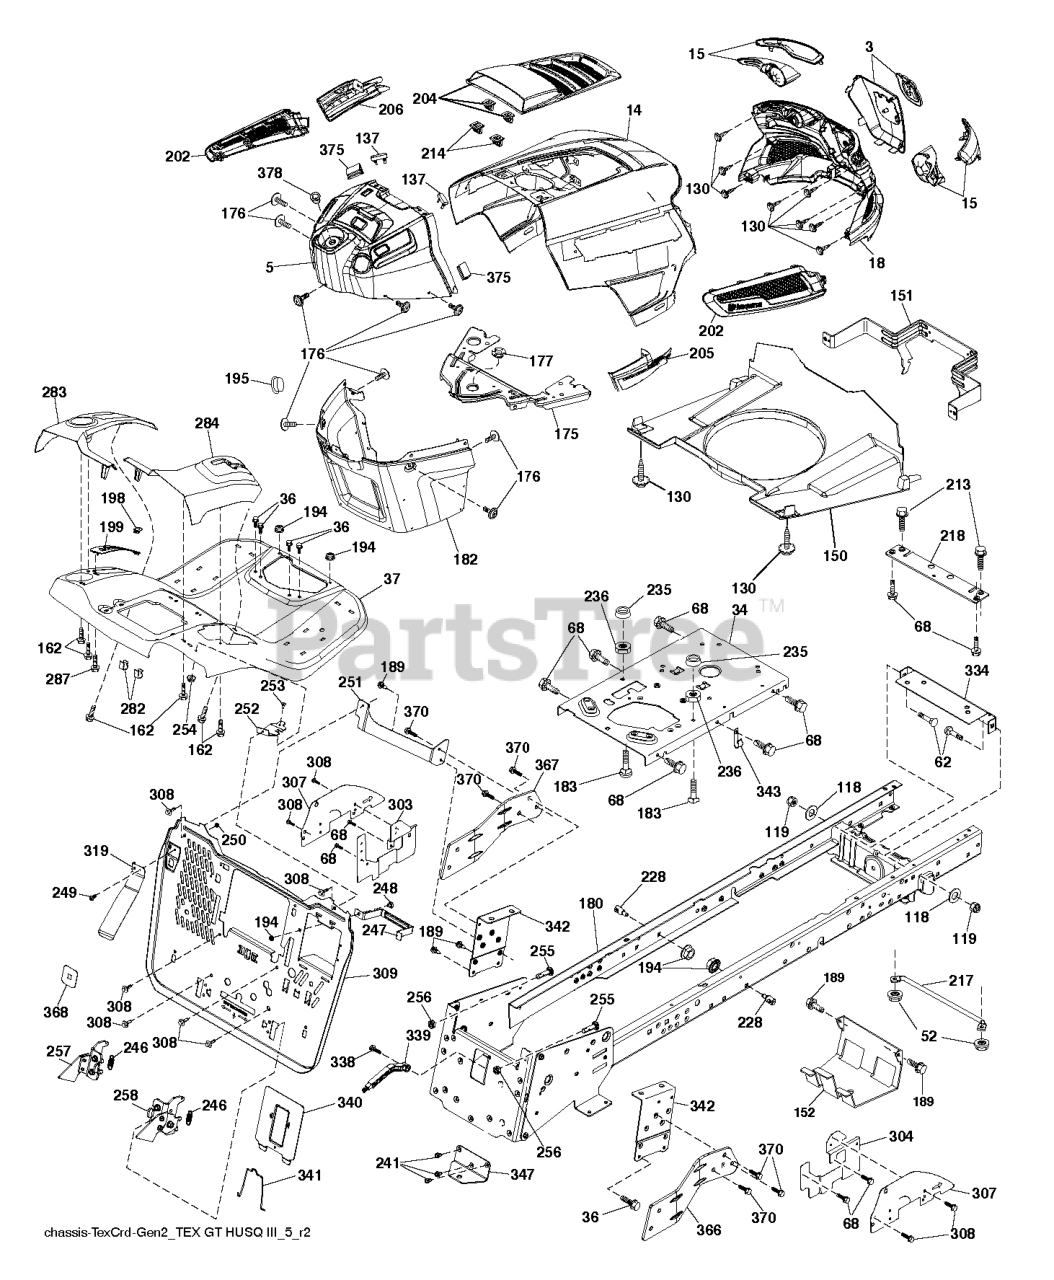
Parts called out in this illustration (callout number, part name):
5	DASH.ASM.W/BUMPERS.READYSTART
14	HOOD.ASM.HUSQVARNA.GT.TEX.ORAN
15	Service Kit
36	SCREW 5/16"
37	FENDER.TEX.SRD.CRD.FRN.GUARDS
118	WASHER PLAIN WASHER 3/8 X 0.08
137	BUMPER DASH
150	AIR.DUCT.GTV.BLACK
151	BRACKET.PIVOT.HOOD.GT.HUSQ.II
152	SHIELD.BROWNING.W/TEX
175	PLATE.PNT.CROSSMEMBER.HUSQ/PRE
176	SCREW.#10-24X5/8.RN.QU
177	BUSHING STEERING
180	CHASSIS WELDMENT.CRD2.BKP_BLTS
182	DASH LOWER.HUSQ.PRED NO CRUISE
189	SCREW
195	PLUG.HOLE.DASH.LOWER.12V.BLK
198	INDICATOR.DECK.LIFT.RED
199	PLATE DECK LIFT
202	Vents
205	SIDE.TRIM.RH.GT.HUSQ.II
206	SIDE.TRIM.LH.GT.HUSQ.II.GRAY
213	SCREW HEXAGON HEAD SCREW 5/16-
214	CLIP.RETAINER.TINNER.
217	ROD.PIVOT.HOOD
218	X-PIECE.HOOD.STOP.NON/
228	STUD.W/"D"ANTI-ROTATION
236	NUT.CENTERLOCK.5/16-
246	SPRING.LTCH.BGR.GEN2.5.CRD.TEX
247	STRAP.BATTERY.TCRD.GEN2.5X431
248	BOLT.CARR.5/16-18X1/2
249	SCREW.BUTTONHD.10-24X1/2.(2 2)
251	BRACKET.PNT.LH.SUPP.BKPLT.EDIP
252	BRACKET.PNT.RH.SUPP.BKPLT.EDIP
253	BOLT CUP HEAD SQUARE NECK BOLT
254	NUT T
257	LATCH.ASM.BGR.LH.GEN2.5.STMPD
258	LATCH.ASM.BGR.RH.GEN2.5.STMPD
282	CLIP.RETAINER.CONSOLE.LT.HUSQ
283	CONSOLE.DECKLIFT.CRDII.498
284	CONSOLE.PEDAL.HYDRO
287	SCREW 1/4X20
303	SHIELD.LWR.LH.30DECK/CRD1&2
304	SHIELD.LWR.RH.30DECK/CRD2PEDAL
307	SHIELD.UPPER.CRD.SRD.ISO
308	BOLT.5/16-18UNCX3/4 W/SEMS.BLK
309	BACKPLATE.TEXCRD2.5.BAGGER.479
319	LEVER.PRSNC.BGR.TEX.CRD.GEN2.1
334	BRACKET.ENGINE
339	LEVER LEVER BAGGER
340	BATTERY.DOOR.TCRD.GEN2.5.MS479
341	LATCH.BATTERY.DOOR.TCRD
342	SUPPORT.PNT.FENDER.CRD.TEX
343	CLIP CLIP
347	HITCH HITCH TOW TEX CRD GEN 2
367	Brackets
368	FULL.LEVER.BAGGER.TEX.CRD
370	SCREW 3/8-16X1
375	BUMPER CLIP-ON. DASH 1"
378	BUSHING FLANGE; PLASTIC
